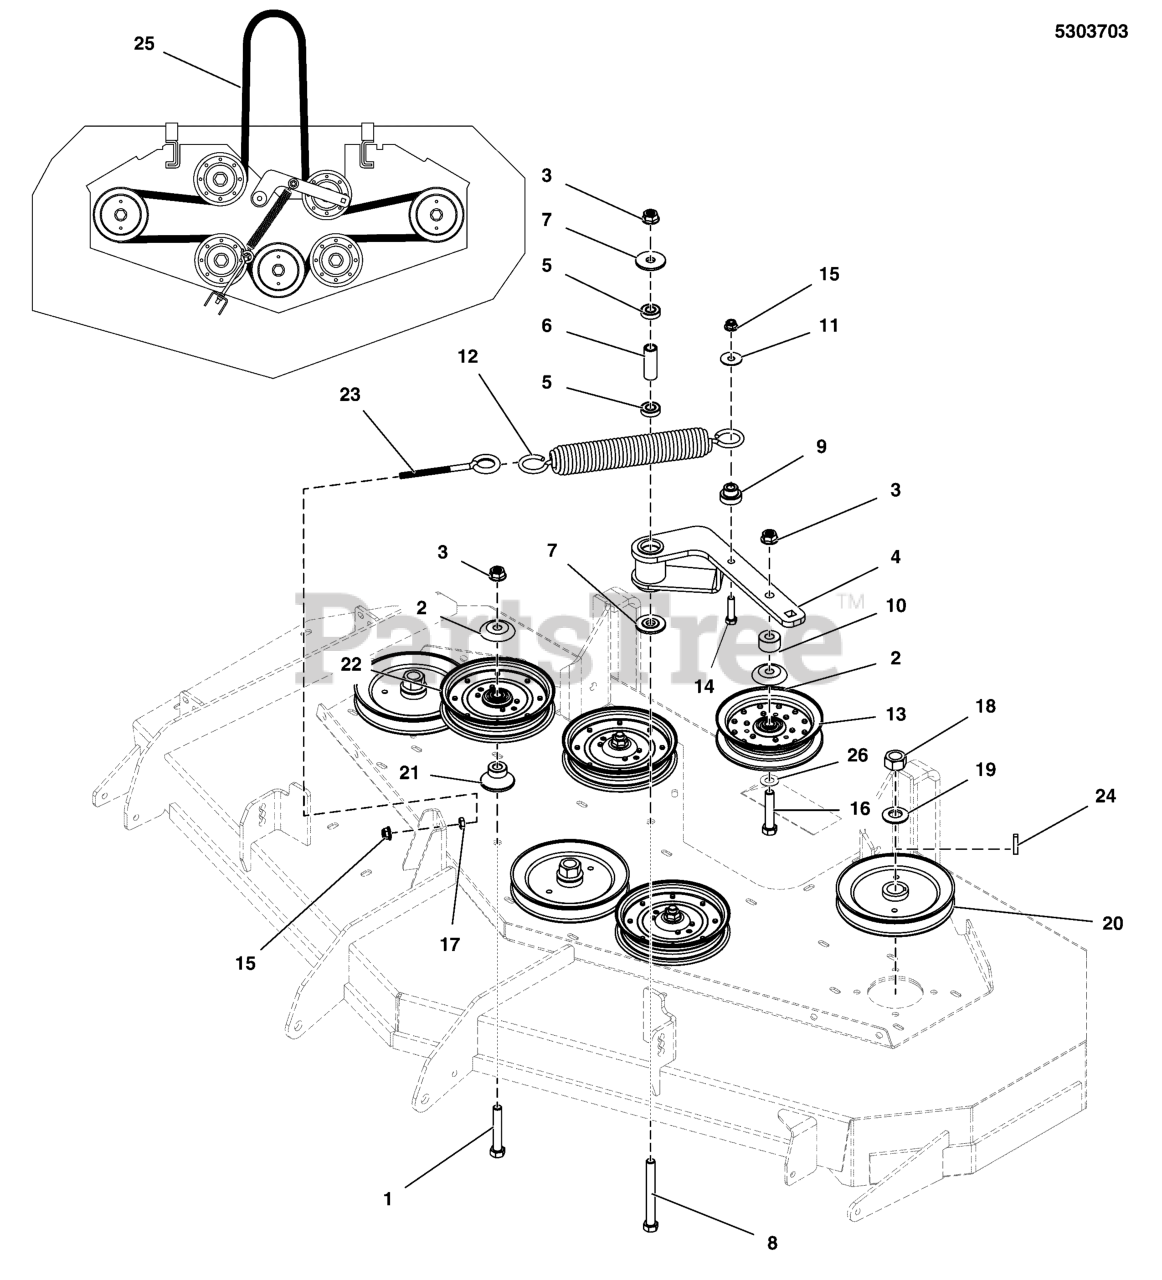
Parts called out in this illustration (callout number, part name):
1	BOLT, 1/2-13 X 3" GD5 CZ
2	SHIELD, PULLEY BEARING, CZ
3	NUT, Hex Flange, Nylock, 1/2-13
4	WELD, TENSION ARM, CUTTER DECK - BLK
5	BEARING, BALL, AXLE
6	SPACER, .505 X .75 X 2.085, CZ
7	SPACER, IDLER ARM, 1/2, PM
8	BOLT, 1/2-13 X 4-1/2 GD5 CZ
9	SPACER, .38 X 1.13 X .781 STEP, CZ
10	SPACER, .52 X 1.25 X .70, CZ
11	WASHER-3/8 FENDER
12	SPRING, EXT, 1.5ODX12.25X.234WIRE BLK
14	BOLT, 3/8-16 X 1-1/2" GD5 CZ
15	NUT, 3/8-16 HEX NYLOCK FLANGE
16	BOLT, 1/2-13 X 2-1/2" GD5 CZ
17	NUT, 3/8-16 HEX SERRATED FLANGE
18	NUT, 3/4-16 HEX
19	WASHER, 3/4 BELLEVILLE
20	PULLEY, 6.93 EOD X 25MM, SPLIT
21	IDLER MOUNT
23	EYE BOLT, 3/8-16 X 6, 3THRD, 1EYE, CZ
24	KEY, 1/4 SQ X 1-1/4
25	BELT, 5V, 163.40EL, LG ARAMID WRPD, RC
26	WASHER, 1/2 SAE
